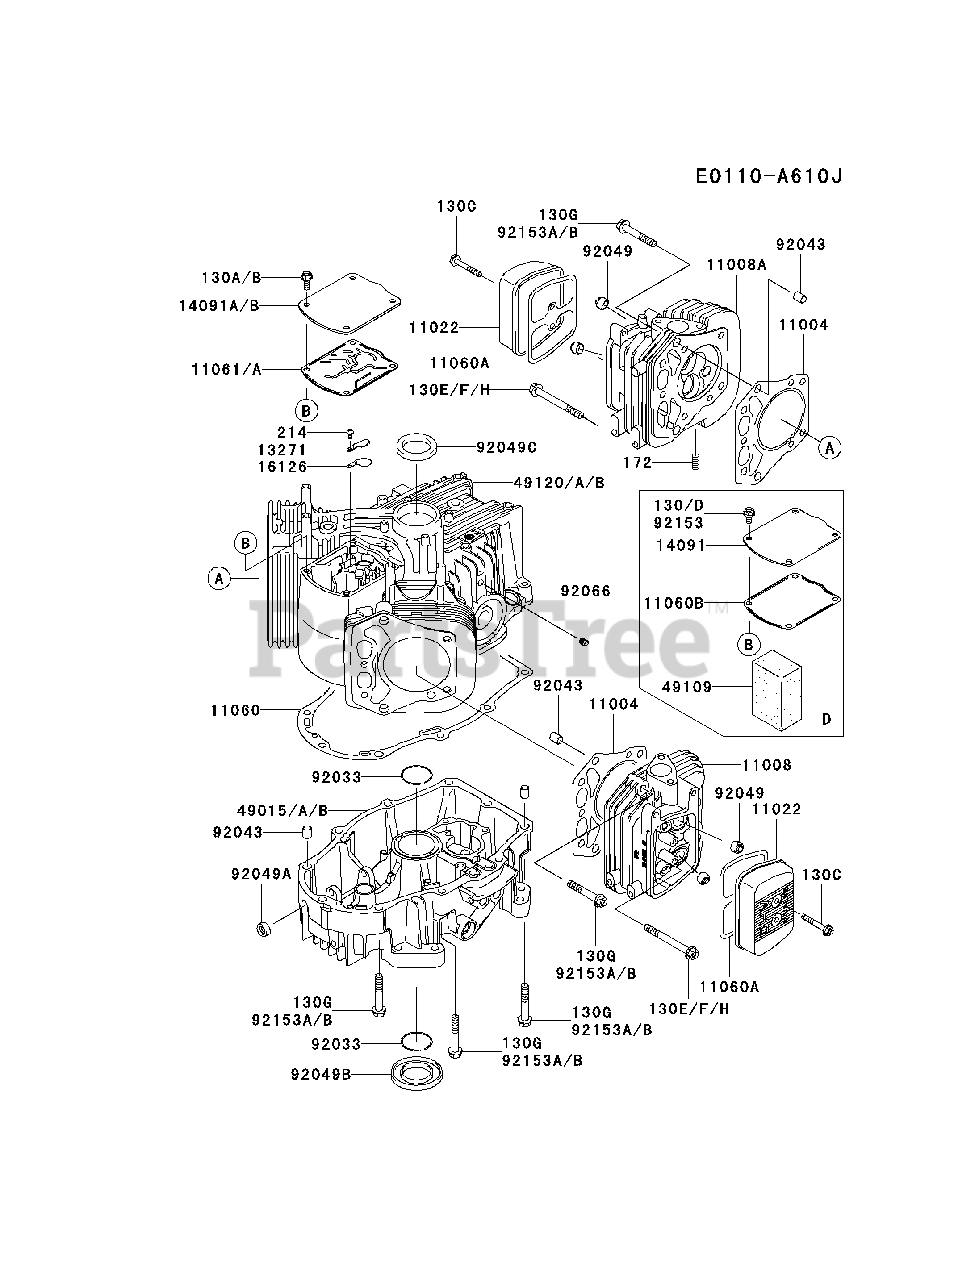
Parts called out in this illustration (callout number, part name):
130A	BOLT-FLANGED,6X16
130C	BOLT-FLANGED,6X40
130E	BOLT-FLANGED,8X75
172	BOLT-STUD,8X18
214	SCREW-PAN+-,4X8
